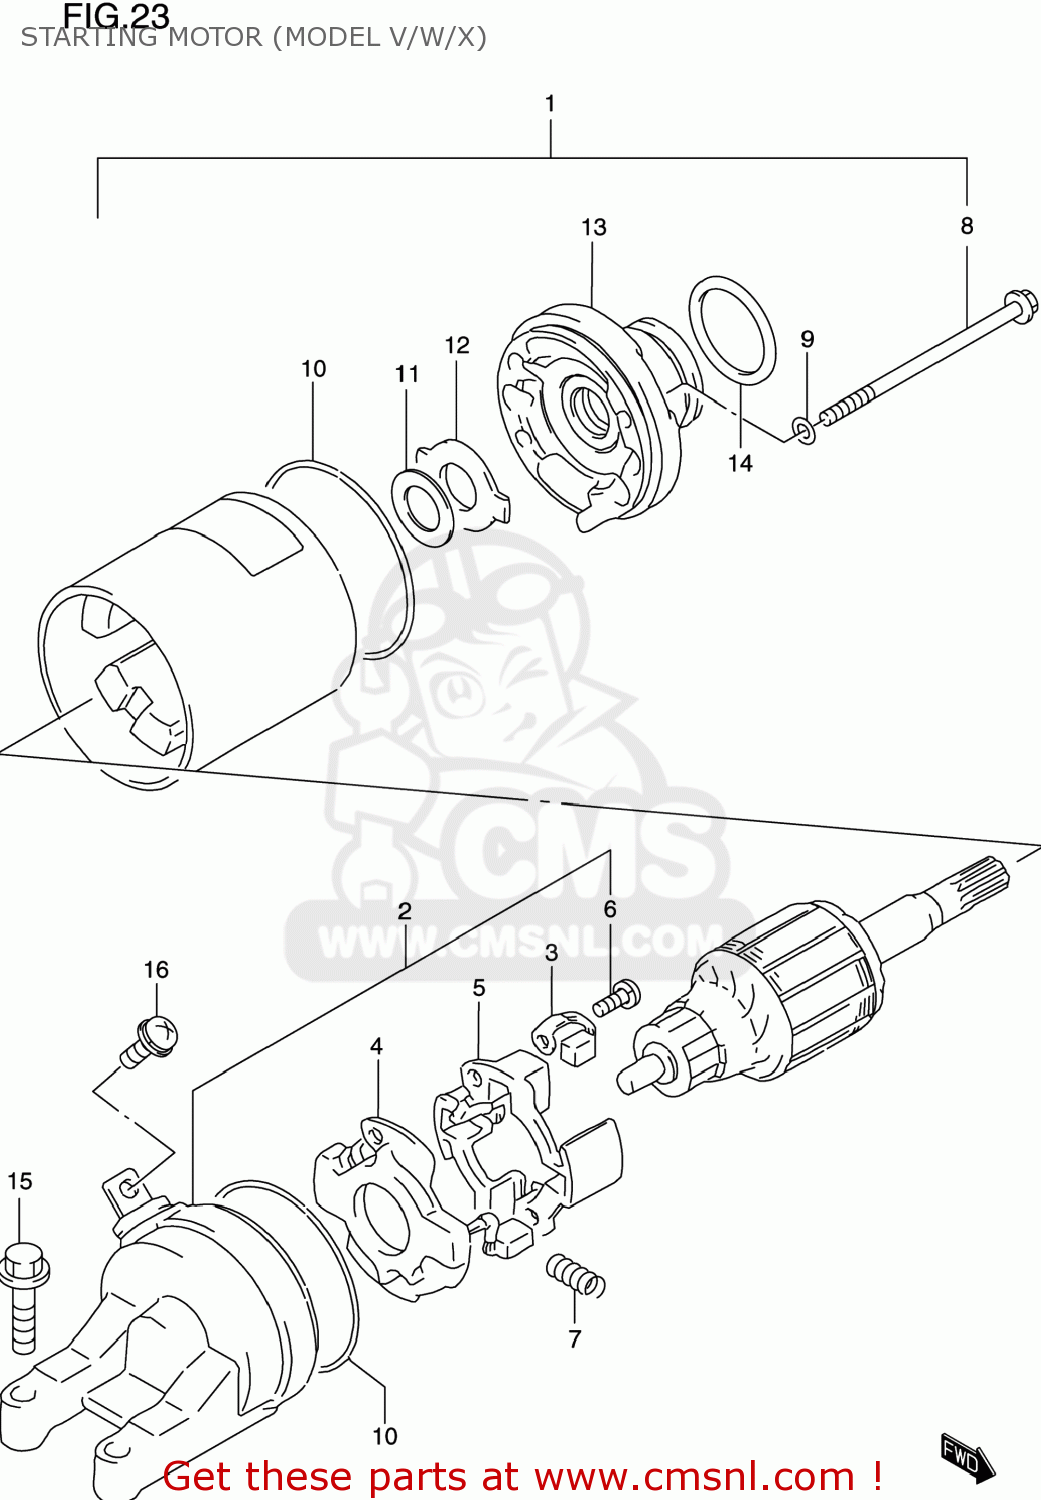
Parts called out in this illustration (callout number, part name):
1	MOTOR ASSEMBLY,STARTING
2	FRAME ASSEMBLY,COMMUTATOR
3	BRUSH
4	BRUSH SUB ASSY,STARTER
5	HOLDER,BRUSH
6	SCREW
7	SPRING
8	BOLT
9	O RING
10	O RING
11	SHIM
12	PLATE,LOCK
13	BRACKET
14	O RING(D:3,ID:24.5)
15	BOLT(6X20)
16	SCREW(5X8)
